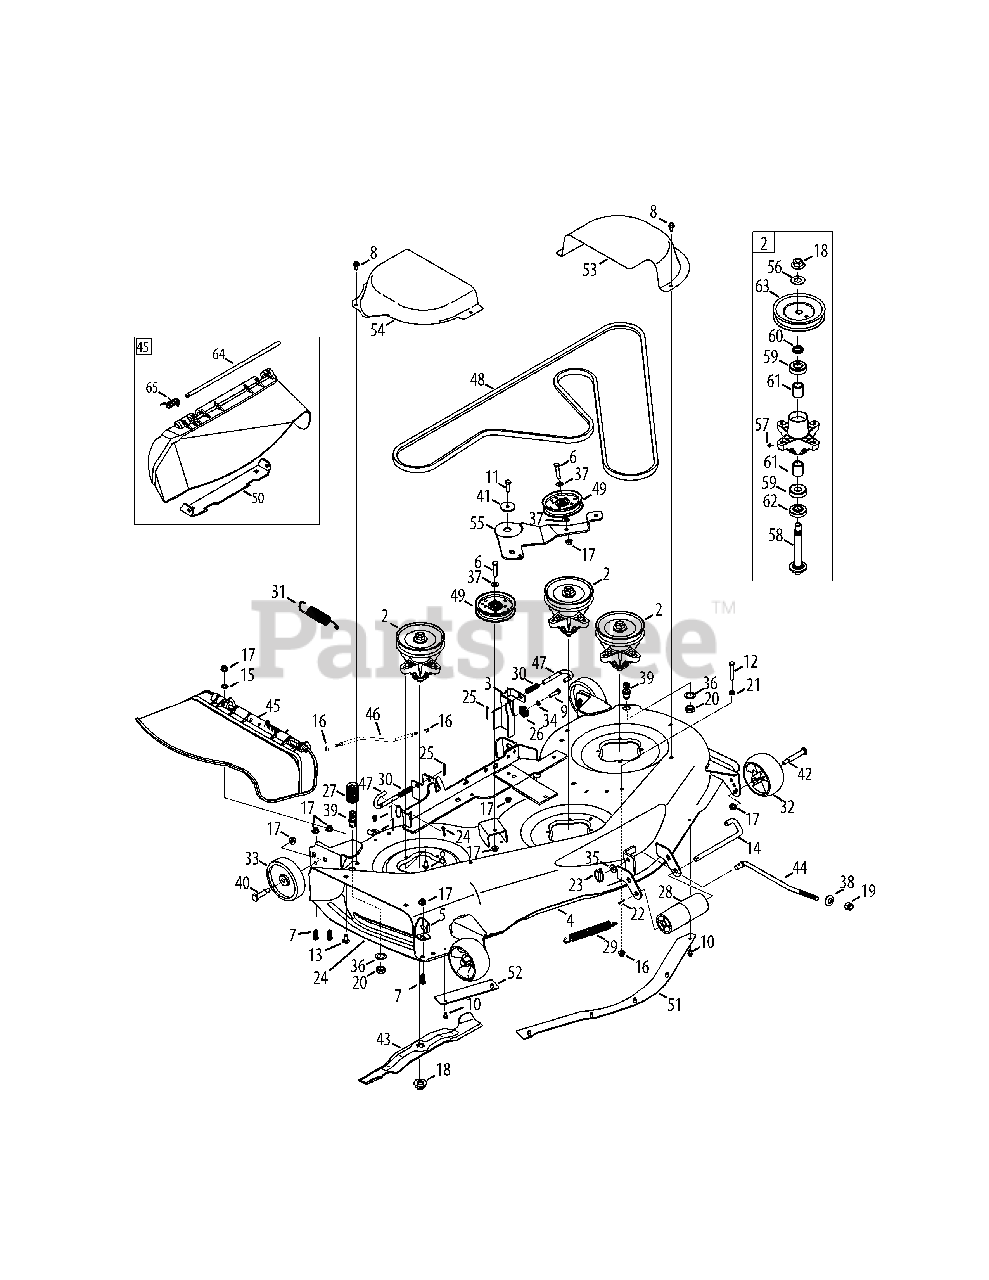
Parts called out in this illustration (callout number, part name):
1	Hook Retainer Bracket
2	Pulley Spindle Assembly, 5.39
3	Deck Hanger Bracket Assembly
6	Hex Screw, 3/8-16:1.75
7	Hex Screw, 3/8-16:1.00
8	Taptite Screw, 5/16-18:.750
9	Hex Screw, 5/16-18:1.25
10	Taptite Screw, 1/4-20:0.500
11	Hex Screw, 3/8-16:1.25
12	Hex Screw, 5/16-18:2.0
13	Carriage Bolt, 3/8-16:0.75
14	Roller Pin, 1/2 DIA x 7.31 LG
15	Push Nut, 3/8
16	Flangelock Nut, 5/16-18
17	Flangelock Nut, 3/8-16
18	Flange Nut, 5/8-18
19	Flexlock Nut, 1/2-13
20	Hex Nut, M16-1.5 DIN 936
21	Hex Nut, 5/16-18:GR5
22	Cotter Pin, 3/32:1.0
23	Lynch Pin, .1875
24	Finger Guard
25	Cotter Pin, 1/8 x 1.25
26	Deck Adjustment Gear
27	Water Nozzle Adaptor
28	Front Roller
29	Extension Spring, .94 DIA. x 6.74 LG
30	Compression Spring, .535 OD x 1.751 LG
31	Extension Spring, 1.15 OD x 5.99 LG
32	Front Deck Wheel
33	Rear Deck Wheel
34	Lock Washer, 5/16
35	Flat Washer, .531 x 1.25 x .100
36	Lock Washer, 5/8
37	Flat Washer, .406 x .875 x .059
38	Bell Washer, .63 x 1.25 x .18
39	Water Nozzle
40	Shoulder Bolt, .496 x 1.525:3/8-16
41	Shoulder Spacer, .8840 x .190
42	Shoulder Bolt, .496 x 2.50:3/8-16
44	Front Deck Lift Rod
45	Chute Assembly
46	Deck Sway Rod
47	Deck Release Handle Rod
48	V Belt
49	Idler Pulley, 4.25"DIA
50	Chute Bracket
51	Center Skirt
52	RH Skirt
53	LH Belt Cover
54	RH Belt Cover
55	Idler Bracket
56	Flat Washer, .760 x 1.50 x .120
57	Lube Fitting
58	Spindle Shaft
59	Ball Bearing, .787ID x 1.85
60	Spacer, .790 ID x 1.25 OD x .175
61	Spacer, .80 x 1.10 x 1.322
62	Spacer, .79 x 1.82 x .55
63	Deck Pulley
64	Hinge Pin
65	Torsion Spring
